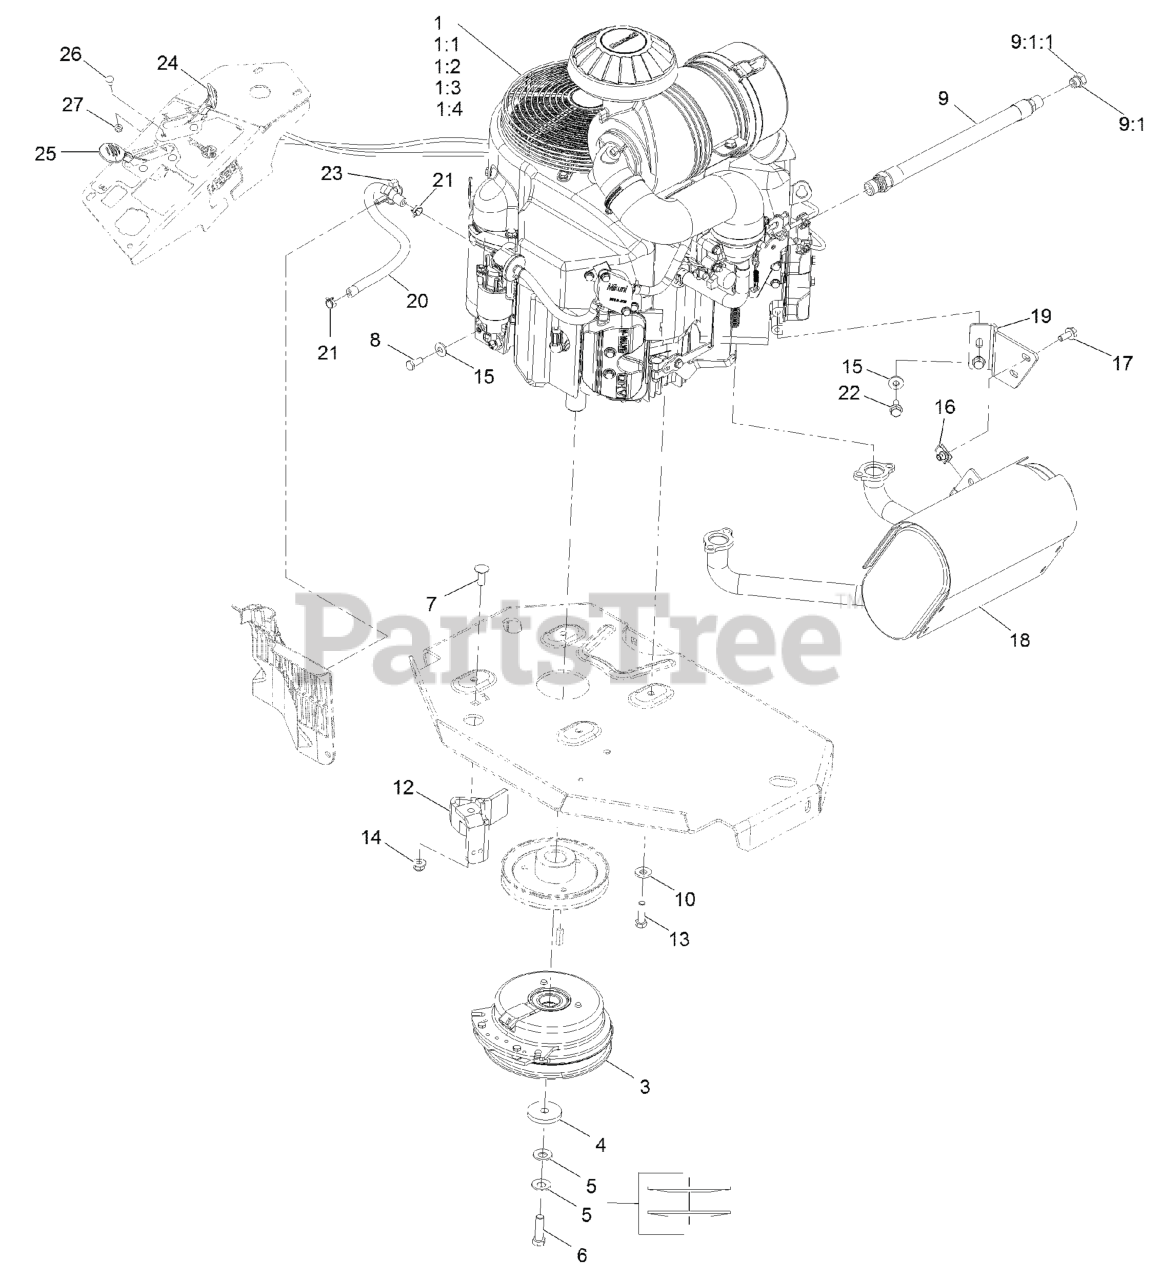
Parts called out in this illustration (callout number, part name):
1:1	Kawasaki 49065-2078 Engine Oil Filter
1:2	Kawasaki 49019-7001 Fuel Filter
1:3	Kawasaki 11013-7039 Safety Filter
1:4	Kawasaki 11013-7038 Air Filter
3	CLUTCH KIT
4	WASHER-CLUTCH
5	WASHER-SPRING
6	SCREW-HH 7/16-20 X 1 1/2 W/LOCTITE
7	SCREW-CARR
8	SCREW-HH
9	ENGINE OIL DRAIN HOSE ASM
9:1	PLUG-HH
9:1:1	O-RING
10	WASHER-BELLEVILLE
12	CLUTCH-ANCHOR
13	SCREW-HH
14	NUT-HF, NI
15	WASHER-SPRING
17	SCREW-HHF
18	MUFFLER
19	BRACKET-MUFFLER
20	HOSE-FUEL
21	CLAMP-HOSE
22	SCREW-HHF
23	CLAMP-HOSE
